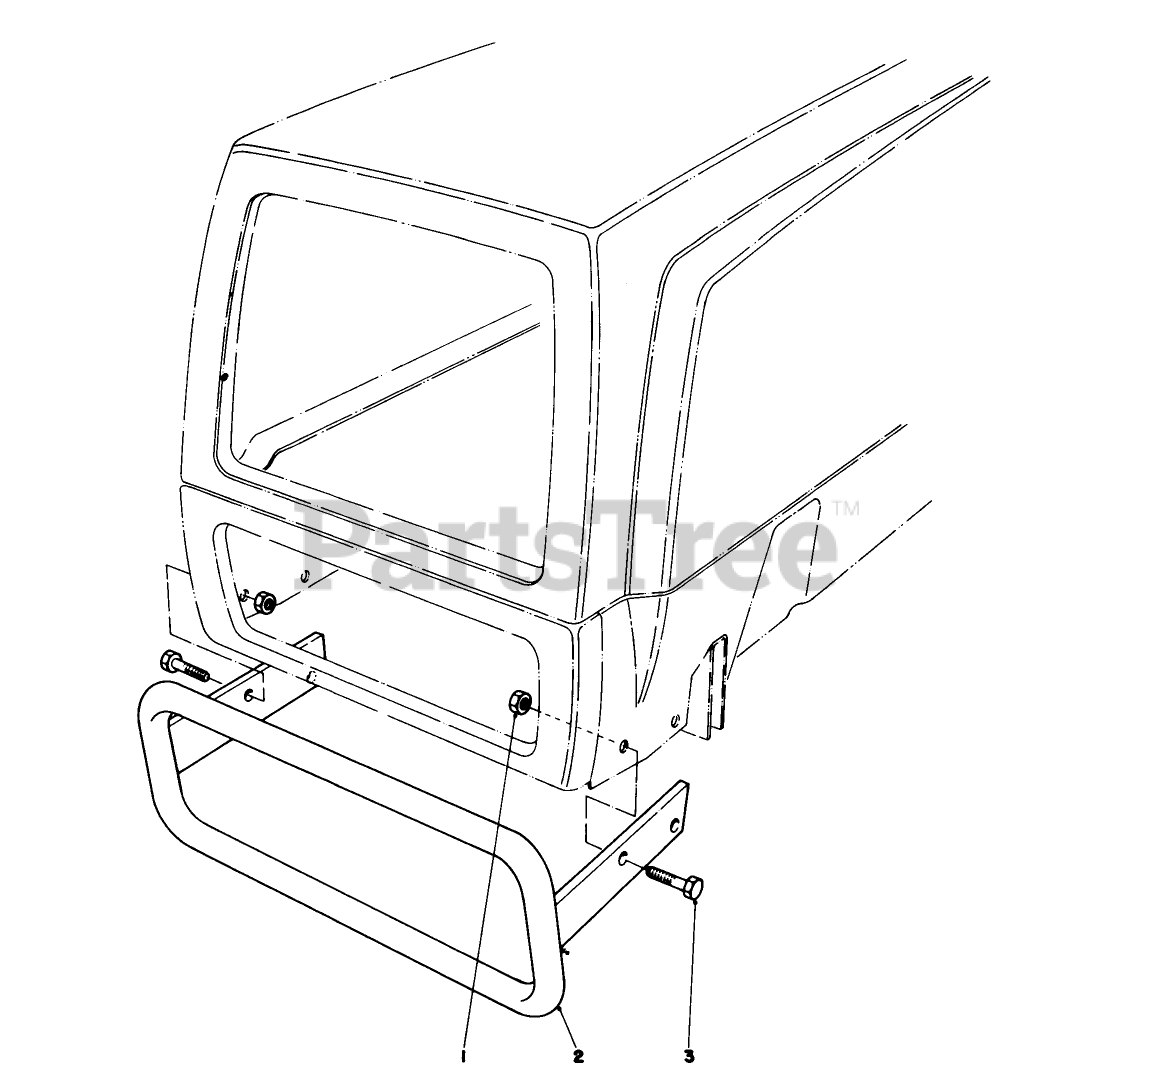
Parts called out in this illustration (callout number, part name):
1	NUT-LOCK, CONE
2	Bumper
3	SCREW-HH
